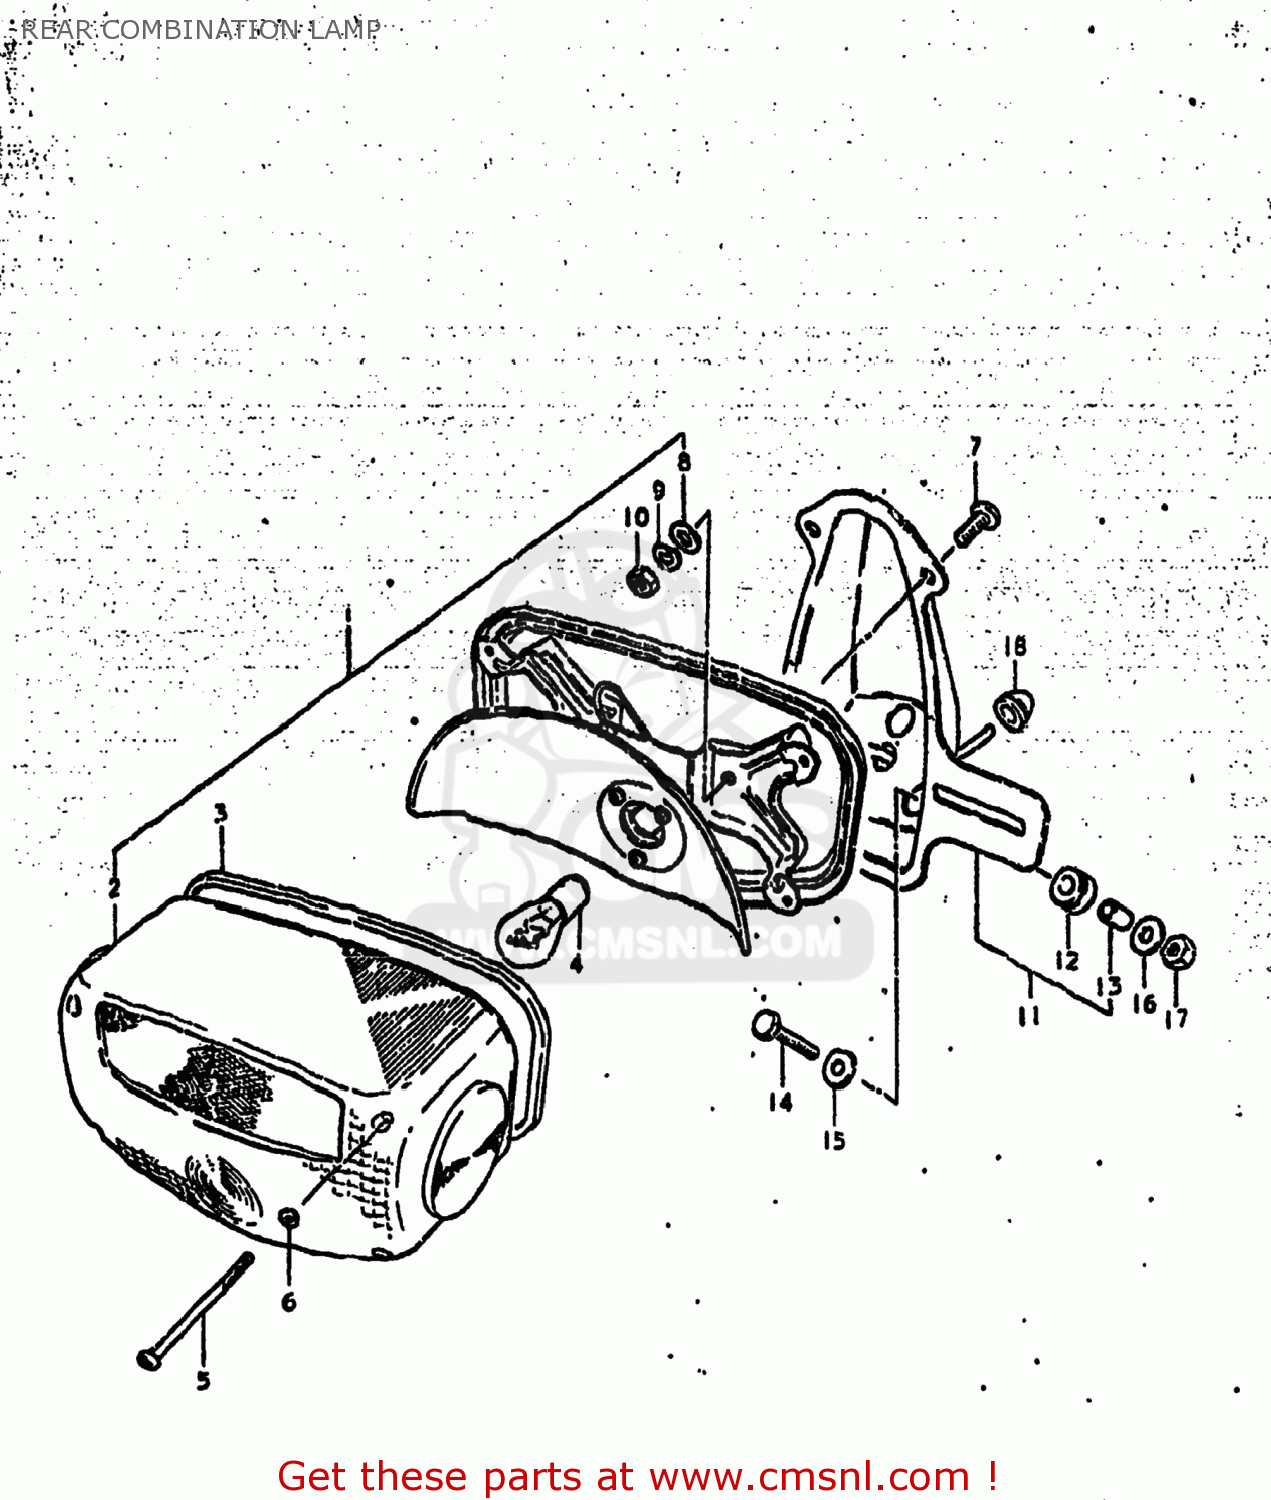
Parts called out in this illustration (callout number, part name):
1	LAMP UNIT,REAR COMBINATION
2	LENS,REAR COMBINATION LAMP
3	GASKET (NAS)
4	BULB(12V23W)
5	SCREW (4X55)
6	GASKET (NAS)
7	SCREW 6X12
8	WASHER
9	LOCK WASHER
10	NUT
11	BRACKET UNIT,TAIL LAMP
12	CUSHION
13	SPACER,REAR COMBINATION LAMP
14	BOLT
15	WASHER (6.5X20X1.2)
16	WASHER
17	NUT
18	GROMMET
